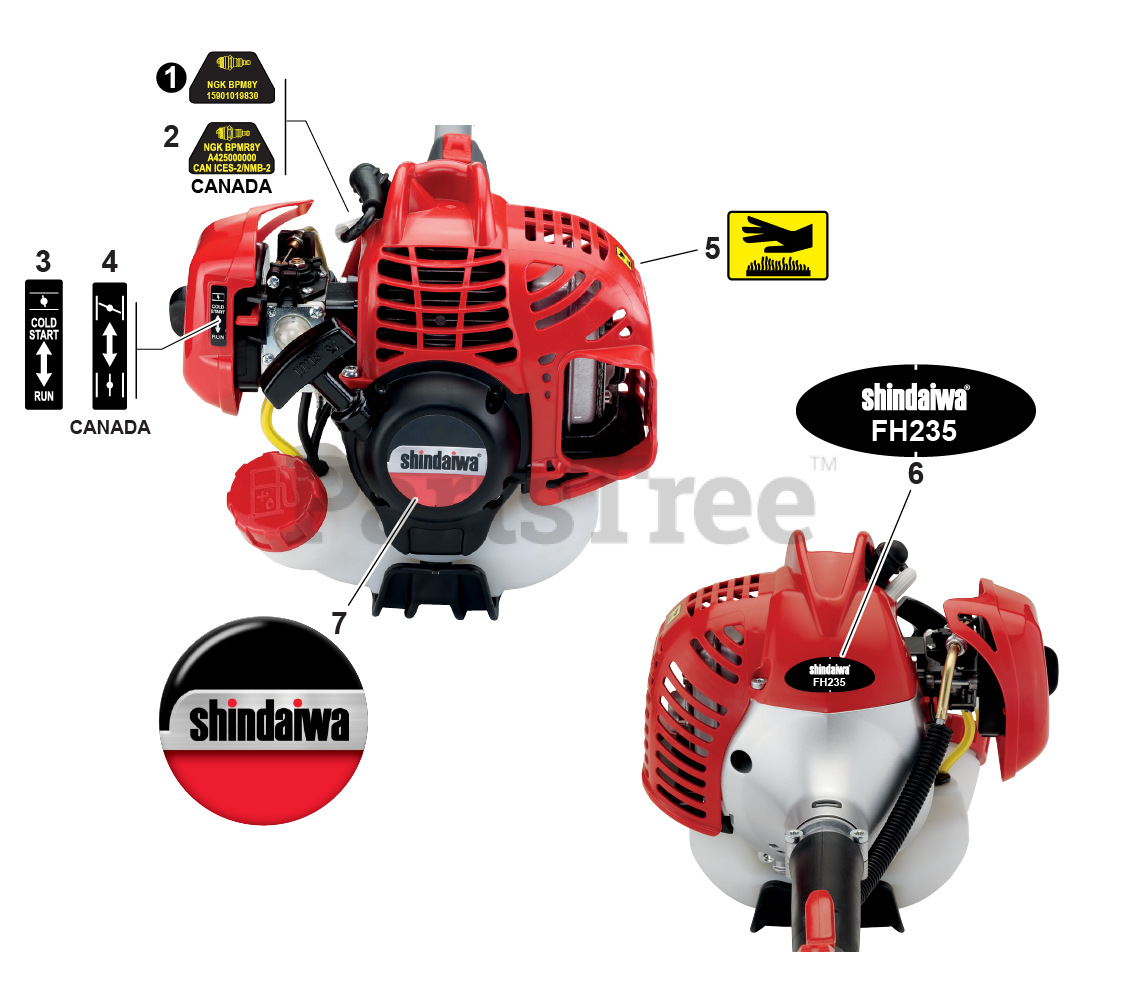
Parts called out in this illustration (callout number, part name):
1	LABEL - SPARK PLUG - BPM8Y
2	LABEL - SPARK PLUG - BPMR8Y
3	LABEL - CHOKE
4	LABEL - CHOKE
5	LABEL - CAUTION - HOT
6	LABEL - MODEL FH235
7	LABEL - SHINDAIWA
